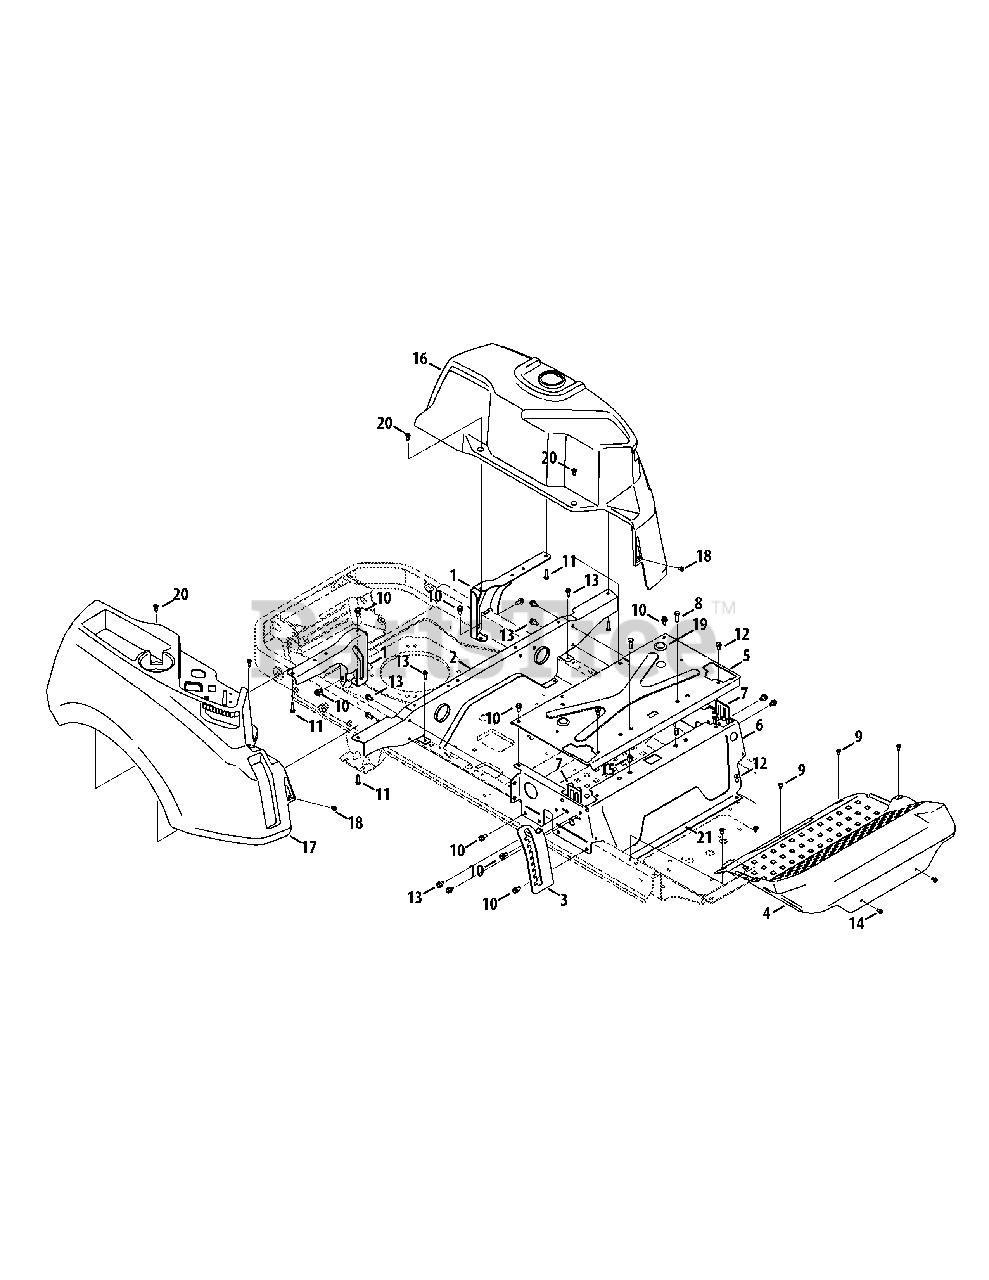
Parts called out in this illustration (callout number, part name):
1	Rear Tank Bracket
2	Rear Seatbox Brace
3	Height Index Bracket
4	Floor Board
5	Seatbox Plate
6	Seat Frame
7	Lapbar Brace Bracket
8	Hex Cap Screw, 5/16-18 x 1.00
9	Self Tapping Screw, 1/4-20 x .50
10	Hex Washer Screw, 5/16-18 x .750
11	Hex Washer Screw, 5/16-14 x 1.00
12	Self Tapping Screw, 5/16-18 x .750
13	Hex Washer Screw, 5/16-18 x .50
14	Screw, Self-Tapping, 5/16-18, 0.750
15	Nut, 5/16-18
16	LH Console
17	RH Console
18	Shoulder Screw, 1/4-20
19	Button Plug
20	Shoulder Screw, .368 x .115, M6-1
